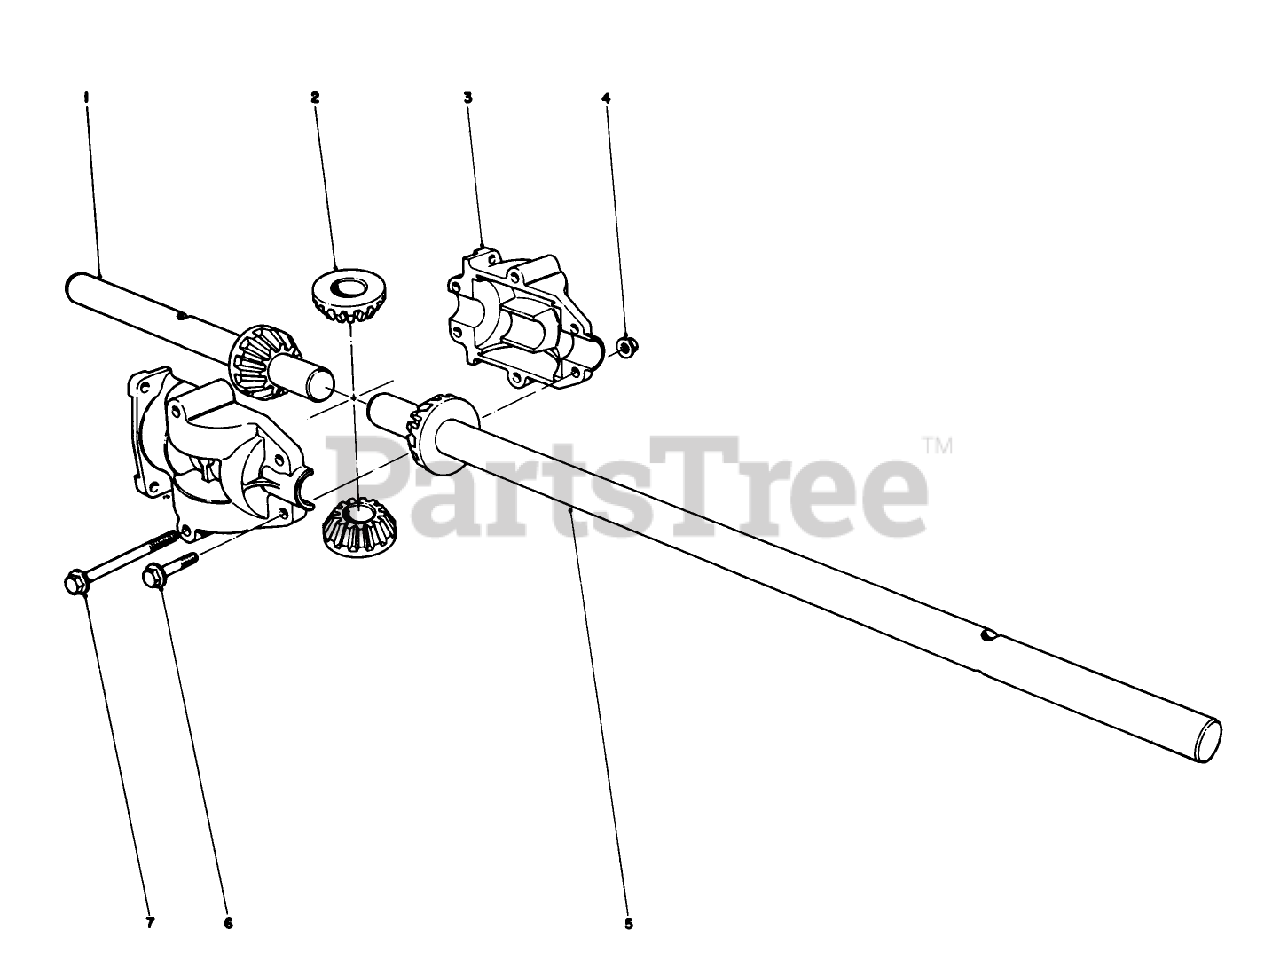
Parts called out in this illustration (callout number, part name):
1	Short Shaft
3	Housing Half
4	NUT-HHF
5	Long Shaft
